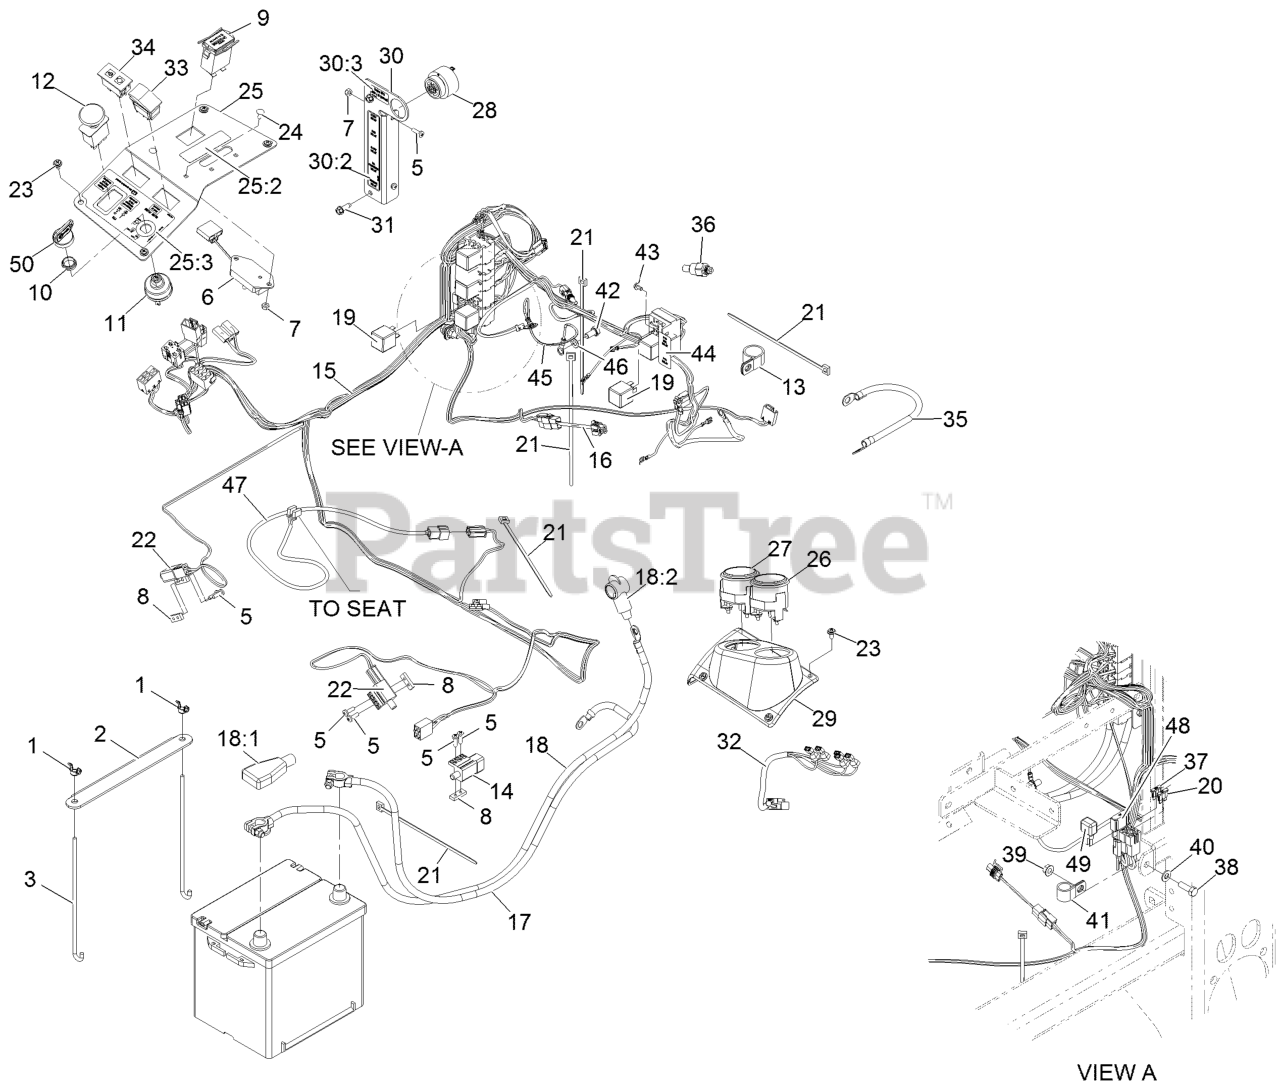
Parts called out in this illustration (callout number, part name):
1	WINGNUT
2	HOLDDOWN-BATTERY
3	BOLT-HOLDDOWN
5	SCREW-PPH
6	MODULE-DELAY, SEAT
7	NUT-LOCK, NI
8	PLATE-TAPPED
9	METER-HOUR
10	NUT-SWITCH, IGNITION
12	SWITCH-PTO, ON-ON
13	CLIP-LOOM
15	HARNESS,WIRING-LZDS KUBOT
16	HARNESS-WIRE
17	CABLE-BATTERY NEGATIVE
18	ASM,POSITIVE BATTERY CABL
18:1	INSULATOR-TERMINAL, BATTE
18:2	INSULATOR-STARTER
20	FUSE-BLADE TYPE, 20 AMP
21	TIE-PLASTIC
22	SWITCH-OPEN, NORMALLY
23	SCREW-PPH
24	BOLT-CARR
25	CONTROL PANEL W/DECALS
25:2	DECAL,THROTTLE ONLY
25:3	DECAL-CONTROL PANEL
26	GAUGE-TEMPERATURE
27	GAUGE-VOLTMETER
28	ALARM-TONE, DUAL
29	BEZEL, GAGE XP LH TANK
30	ASM,RELAY BRKT W/ DECALS
30:2	DECAL,RELAY KUBOTA
31	SCREW-HWHTF
32	HARNESS-GAUGE
33	SWITCH-ROCKER
34	LAMP-WARNING
35	CABLE-ENGINE NEGATIVE
36	SENDER,TEMPERATURE
37	FUSE-40 AMP
38	SCREW-HH
40	WASHER-PLAIN
41	CLIP-LOOM
42	SCREW-HH
43	SCREW-HWH
44	DECAL-RELAY DIESEL
45	GROUND WIRE ASM
46	WASHER-LOCK
47	HARNESS-WIRING, SEAT
48	FUSE-BLADE, 50 AMP
50	KEY-IGNITION
